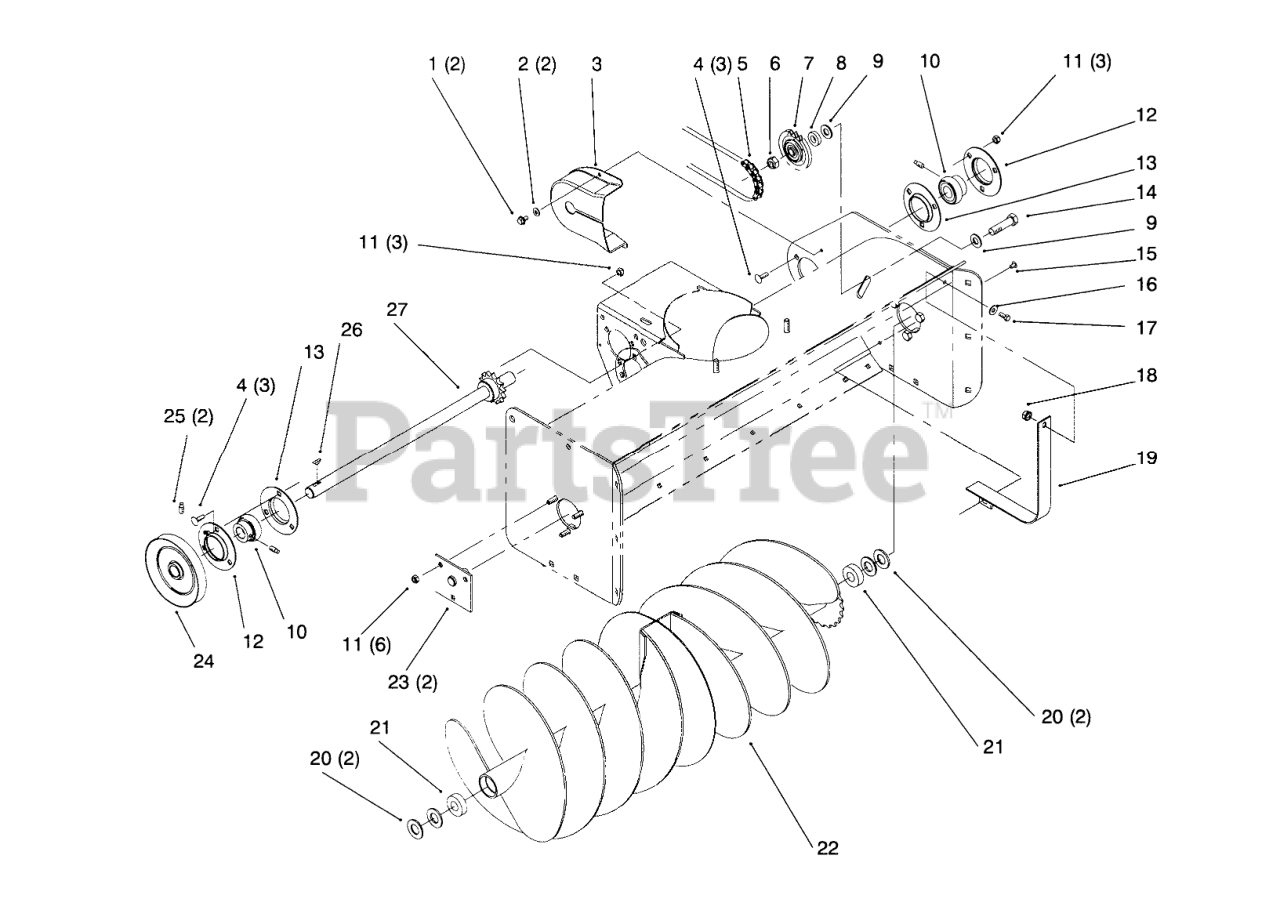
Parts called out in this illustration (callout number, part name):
1	SCREW-HWH
2	WASHER-FLAT
3	GUARD-CHAIN
4	BOLT-CARR
5	CHAIN-64 PITCHES
6	NUT-LOCK, NI
7	Idler Sprocket
8	SPACER
9	WASHER-FLAT
10	BEARING AND COLLAR
11	NUT-LOCK, NI
12	FLANGE-ZERK RELUBE
13	Flange
14	SCREW-HH
15	SCREW
16	WASHER-FLAT
17	SCREW-HH
18	NUT-KEPS
19	GUARD-INNER
20	WASHER-FLAT
21	BEARING-BALL
22	Auger
23	SUPPORT
24	PULLEY
25	SCREW-SQH
26	Key
27	SHAFT W/SPRKT
